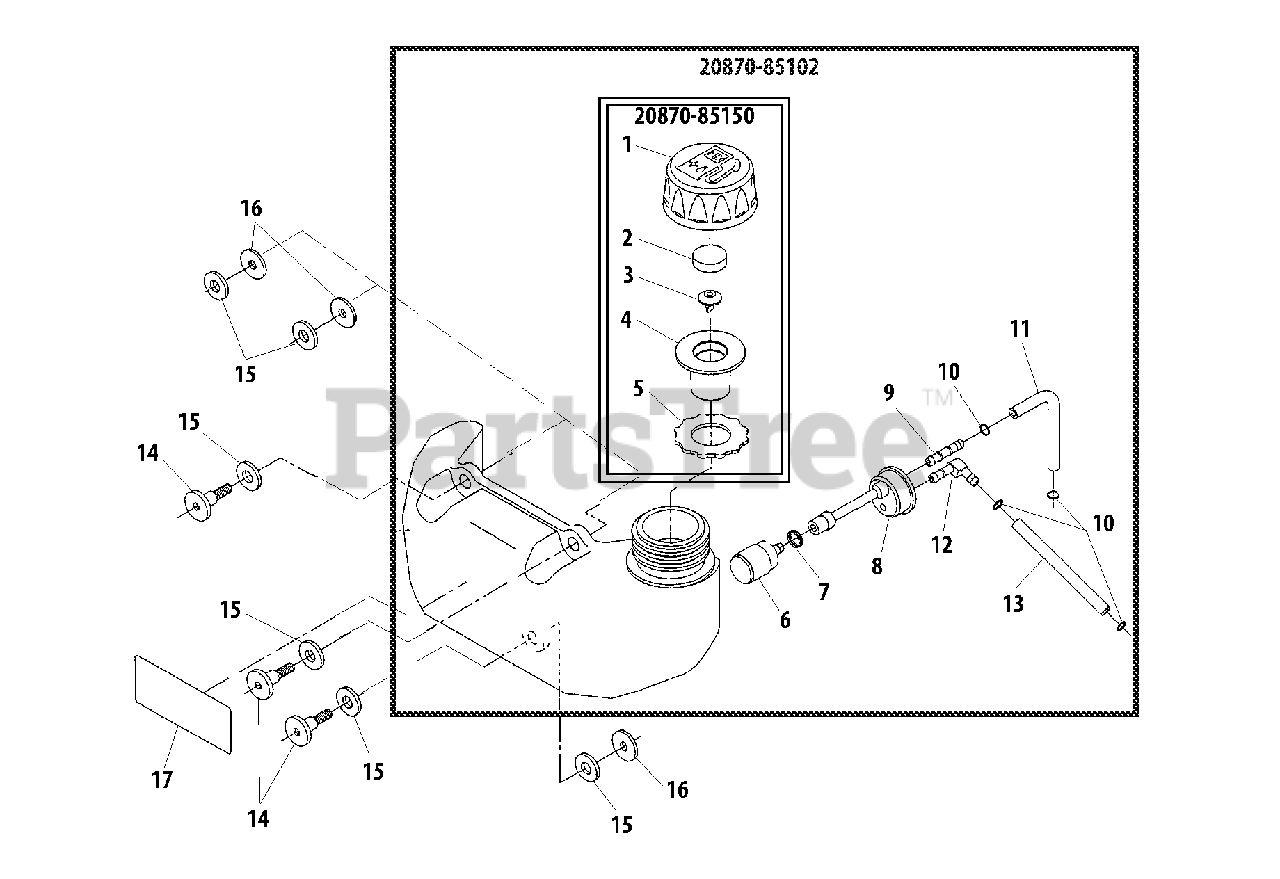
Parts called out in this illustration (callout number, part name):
1	CAP, FUEL
2	COVER, VENT
3	VENT
4	HOLDER, VENT
5	GASKET, CAP
6	FILTER, FUEL
7	RING, RETAINING
8	FUEL PIPE ASSY
9	CONNECTOR, PIPE
10	RING, RETAINING - 6
11	PIPE - FUEL
12	CONNECTOR, PIPE
13	PIPE - RETURN
14	BOLT
15	WASHER
16	COLLAR
17	LABEL - CAUTION
20870-85102	FUEL TANK ASSY
20870-85150	CAP ASSY
